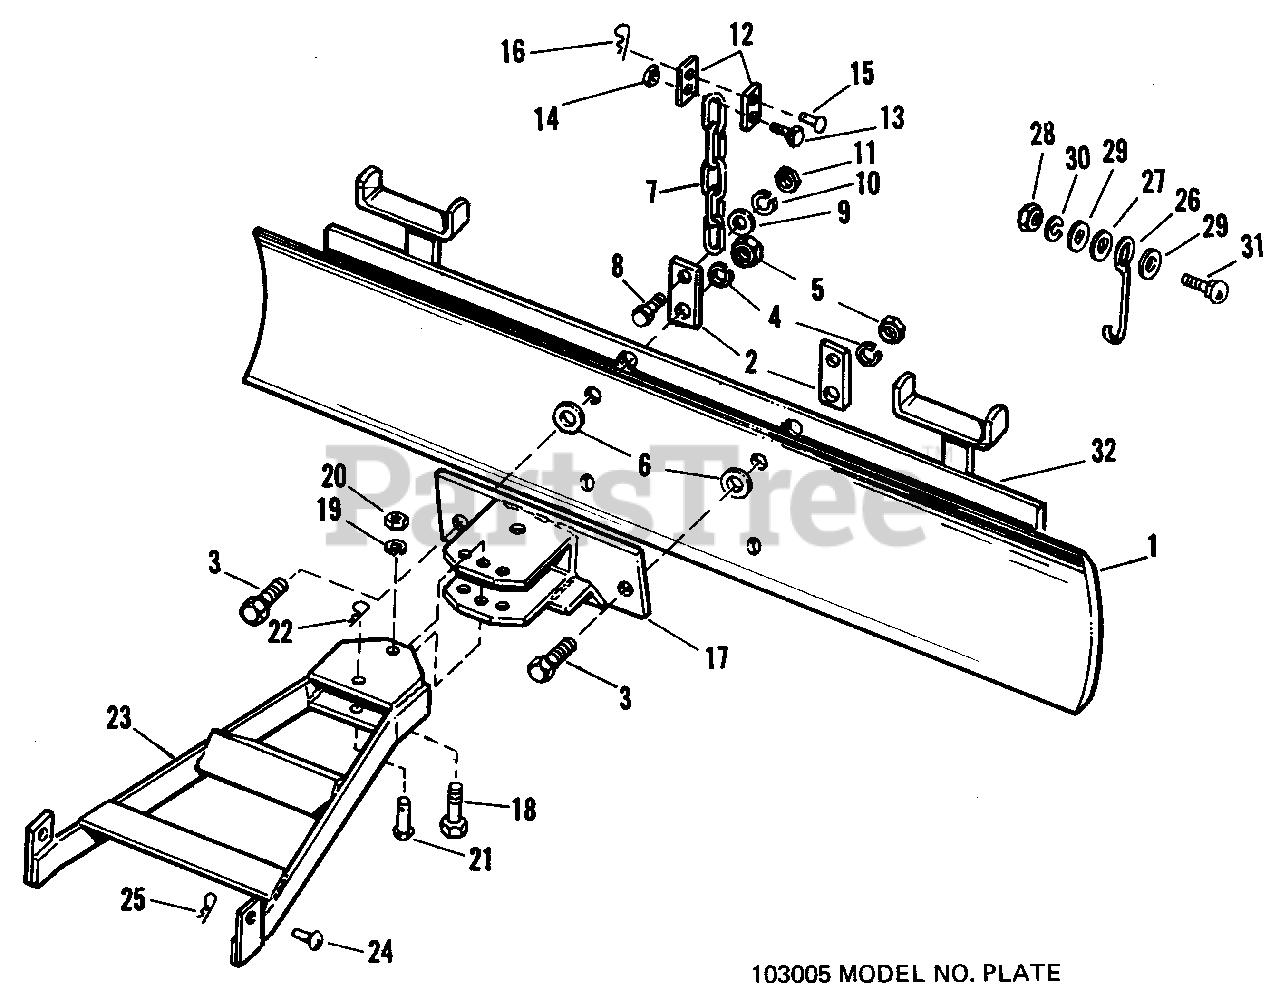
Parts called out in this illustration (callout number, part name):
1	Grader Blade
3	Hex Capscrew, 5/8"-11 x 3" lg.
4	Lock Washer, 5/8"
5	Hex Nut, Full, 5/8"-11
7	Chain
8	Hex Capscrew, 3/8"-16 x 1-1/4" lg.
9	Plain Washer, 3/8"
10	Lock Washer, 3/8"
11	Hex Nut, Full, 3/8"-16
13	Hex Capscrew, 3/8"-16 x 1" lg.
14	Hex Nut, Full, Lock, 3/8"-16
16	Spring Clip
17	Hitch Assembly
18	Hex Capscrew, 5/8"-16 x 3" lg.
19	Lock Washer, 5/8"
20	Hex Nut, Full, 5/8"-16
22	Spring Clip
23	Draw Bar Assembly
24	Pin
25	Spring Clip
27	Nylon Washer
28	Hex Nut, Jam, 5/16"-18
29	Plain Washer, 5/16"
30	Lock Washer, 5/16"
31	Carriage Bolt, 5/16"-18 x 1-1/4" lg.
32	Bracket Assy.
32	I.D. Plate No.
